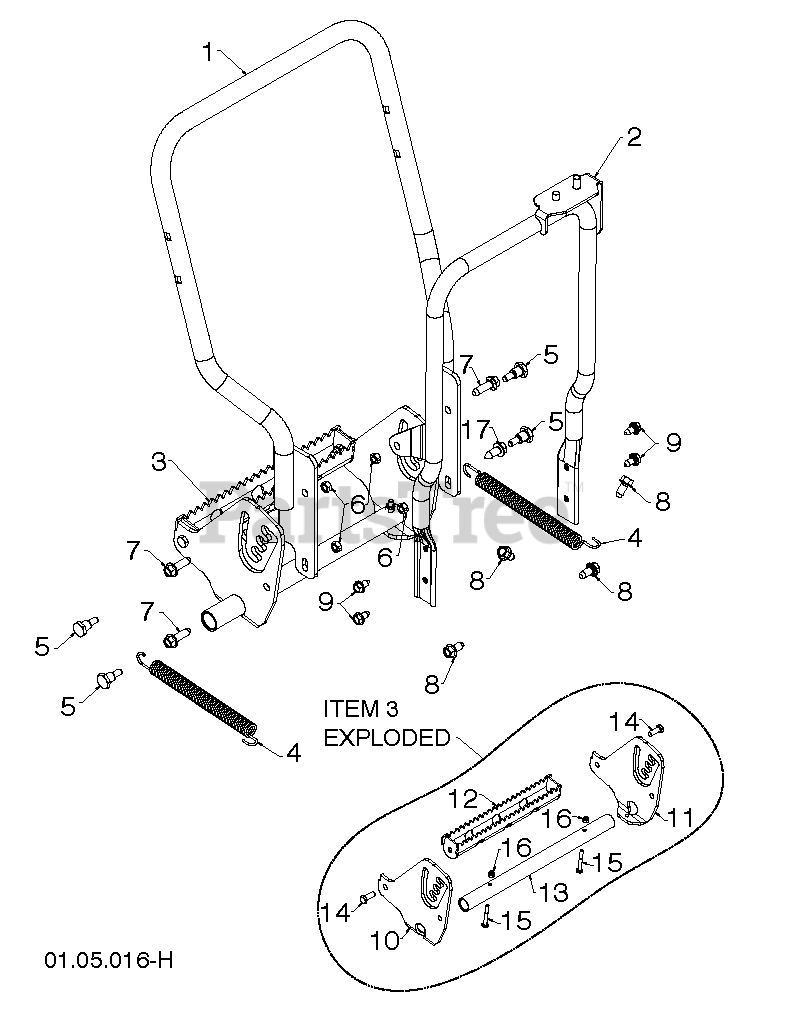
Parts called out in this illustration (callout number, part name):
1	HANDLE.ASM.LOWER.TRACK.GREY
2	SUPPORT.WELDMENT.ROTATOR.BLACK
3	PLATE.FOOT.ASM.SNOW
4	SPRING.EXTENSION.TRACK.SNOW
5	SHOULDERBOLT5/1618
6	NUT.CENTERLOCK.5/16-
7	SCREW.3/8-16
8	SCREW, 3/8-16X3/4
9	BOLT.5/16HEX.WHS.HD
10	FOOT.ADJUST.PLATE.GUIDE.RH.SNO
11	FOOT.ADJUST.PLATE.GUIDE.LH.SNO
12	TRACK.FOOT.ADJ.ASM.SNOW
13	COVER.TRACK.SNOW
15	BOLT.HEX.FINISHED.1/4-20
16	LOCKNUT.NYLOC.1/4-20
17	SCREW THDROL 3/8-16 X 1-1/2
